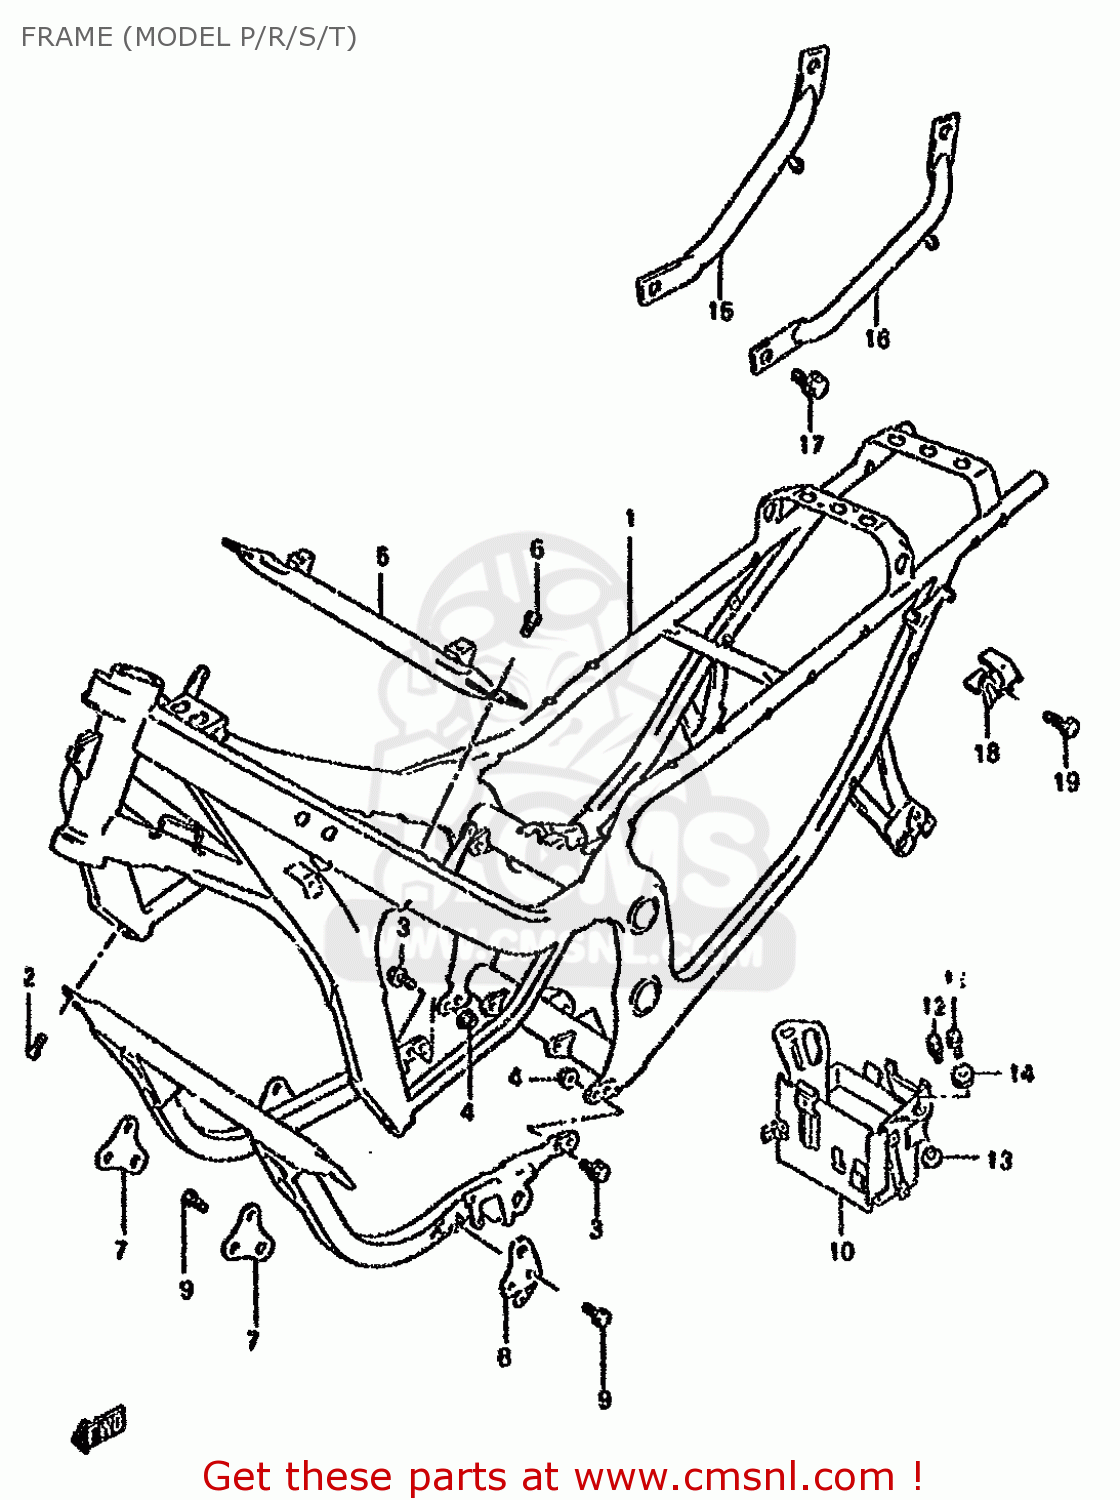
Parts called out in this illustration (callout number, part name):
1	FRAME COMP
2	BOLT
3	BOLT
4	NUT
5	TUBE,FRAME BRIDGE NO.2
6	BOLT(8X20)
7	PLATE,ENG MTG NO.1
8	PLATE,ENG MTG NO.2,L
9	BOLT
10	HOLDER,BATTERY
11	BOLT L:30
12	BOLT
13	SPACER COMP,BATTERY
14	CUSHION
15	GRIP,REAR,RIGHT
16	GRIP,REAR
17	BOLT
18	CUSHION
19	BOLT
20	GRIP,REAR
21	BOLT, LOWER
22	HOLDER,HELMET
23	BOLT
24	WASHER,LOCK
